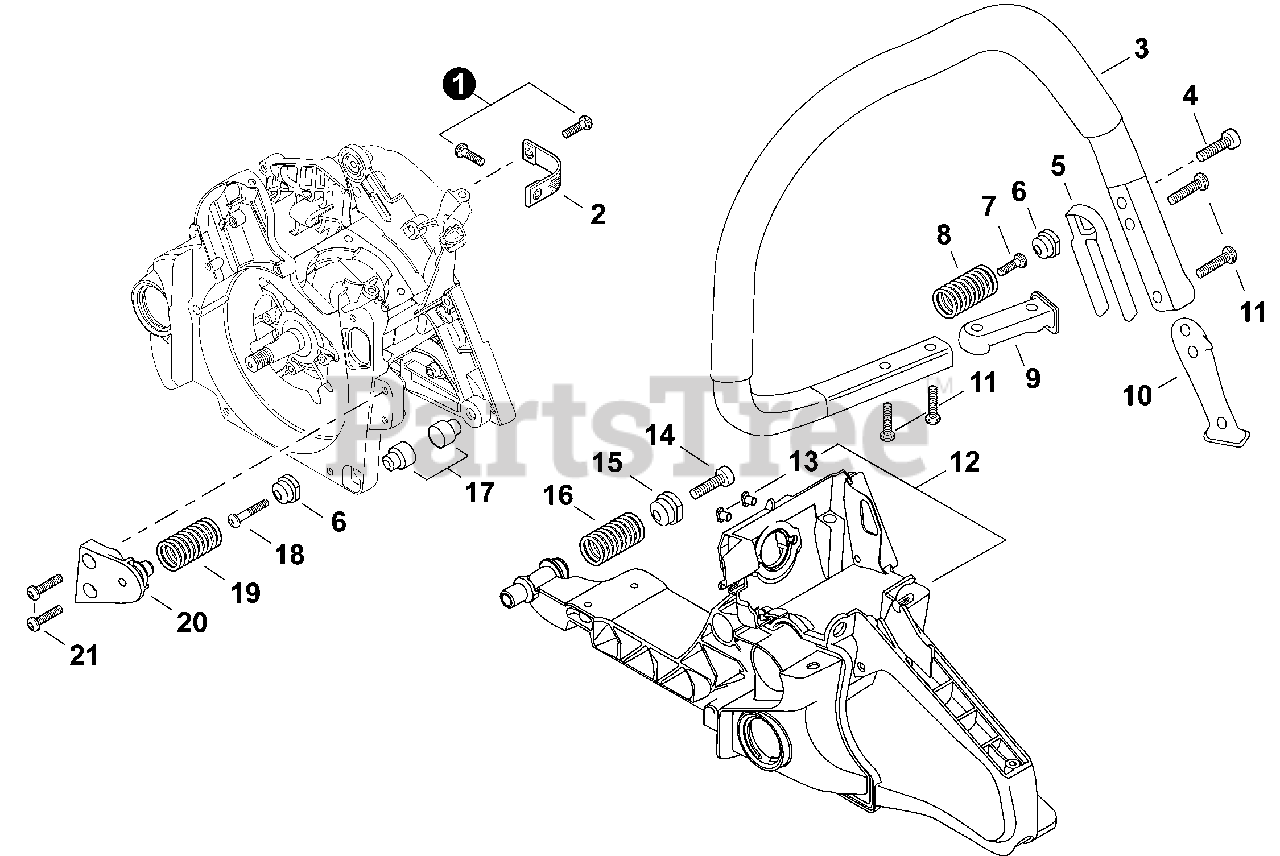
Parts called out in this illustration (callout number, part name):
1	BOLT, TORX 5×16
2	STRAP, SAFETY
3	HANDLE, FRONT
4	BOLT, TORX 6×20
5	HOLDER, SPRING
6	HOLDER, SPRING Ø14.4
7	BOLT, TORX 5×16
8	SPRING, COMPRESSION Ø17×38.4×2.6
9	MOUNT, HANDLE
10	MOUNT, HANDLE
11	BOLT, TORX 5×20
12	HANDLE, REAR
14	BOLT, TORX 6×20
15	HOLDER, SPRING Ø17
16	SPRING, COMPRESSION Ø20×40×3.3
17	CUSHION
18	BOLT, TORX 5×25
19	SPRING, COMPRESSION Ø17×36.7×2.6
20	HOLDER, SPRING
21	BOLT, TORX 5×20
